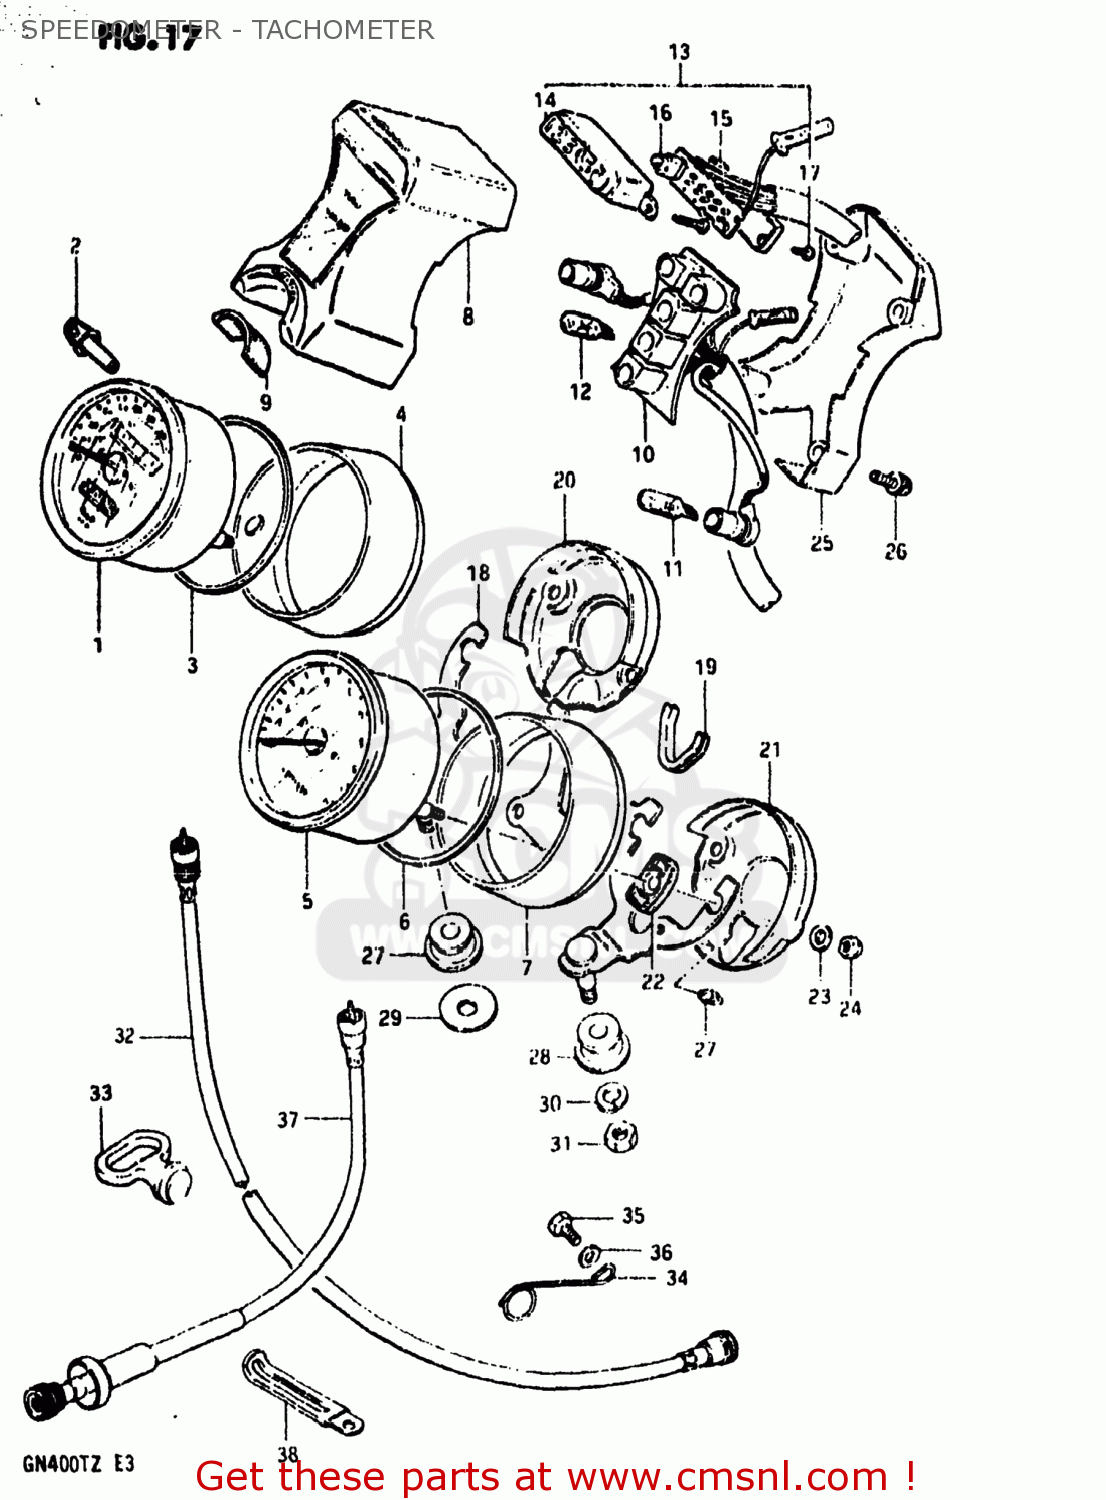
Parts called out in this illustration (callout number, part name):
1	METER,SPEEDOMETER
2	KNOB
3	CUSHION
4	COVER,SPEEDOMETER
5	TACHOMETER
6	CUSHION
7	COVER,TACHOMETER
8	BOX,PILOT
9	SEAL,IGNITION SWITCH
10	SOCKET
11	BULB(6V,3W)
12	BULB(6V1.7W,STANLEY,A61A)
13	INDICATOR ASSEMBLY,GEAR
14	CASE,GEAR INDICATOR
15	COVER,LWR
16	BULB(7V1.1W,BQ041-27503B)
17	SCREW,GEAR INDICATOR
18	BRACKET,METER
19	BRACKET,COVER
20	ORNAMENT,SPEEDOMETER
21	COVER,TACHOMETER
22	CUSHION,METER
23	WASHER
24	NUT
25	COVER,PILOT BOX LWR
26	SCREW,PILOT BULB CASE
27	CUSHION
28	CUSHION,METER BRACKET
29	WASHER (8.5X29X1.6)
30	LOCK WASHER
31	NUT
32	CABLE ASSEMBLY,SPEEDOMETER
33	GUIDE,CABLE
34	CLAMP,SPEEDOMETER CABLE
35	BOLT, UPPER
36	WASHER
37	CABLE ASSEMBLY,TACHOMETER
38	CLAMP L:35
